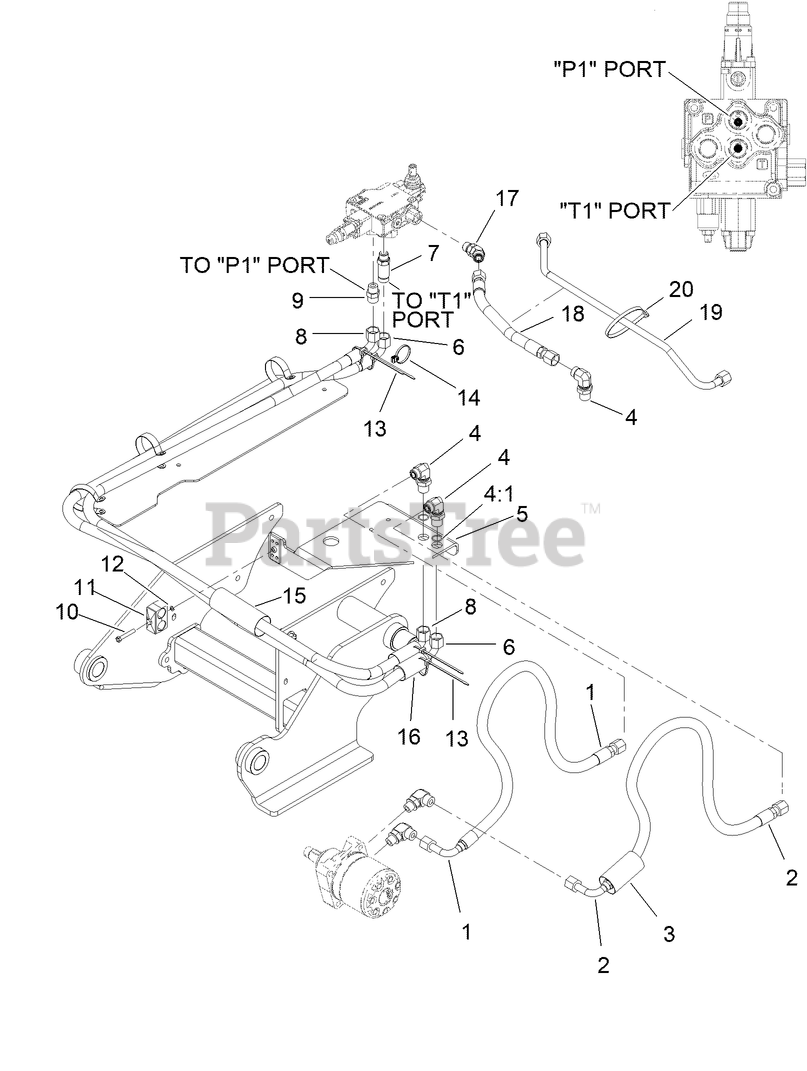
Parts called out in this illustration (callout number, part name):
1	HOSE (10OFX90L-44"-3000)
2	HOSE (10OFX90L-44"-3000)
3	ABRASION SLEEVE (2.07" X 44")
4	FITTING-BULKHEAD, 90 DEG
4:1	O-RING
5	HOSE MOUNT BRACKET
6	HOSE (10OFX90S-10OFX90S-88"-3000)
7	CONNECTOR (10O-10S, LG)
8	HOSE (10OFX90S-10OFX90S-83"-3000)
9	CONNECTOR (10S-10O)
10	SCREW-HH
11	CLAMP SET (3-D-1"-5/16-18)
12	WASHER-LOCK
13	TIE-CABLE
14	EDGE CLIP TOP PERPENDICULAR (.04-.12)
15	ABRASION SLEEVE (2.07" X 60")
16	ABRASION SLEEVE (1.59" X 24")
17	CONNECTOR (10S-10O45)
18	HOSE (10OFX-16"-3000)
19	HARDLINE (-10 HYDRABORER TO TRENCHER)
20	TIE-CABLE
